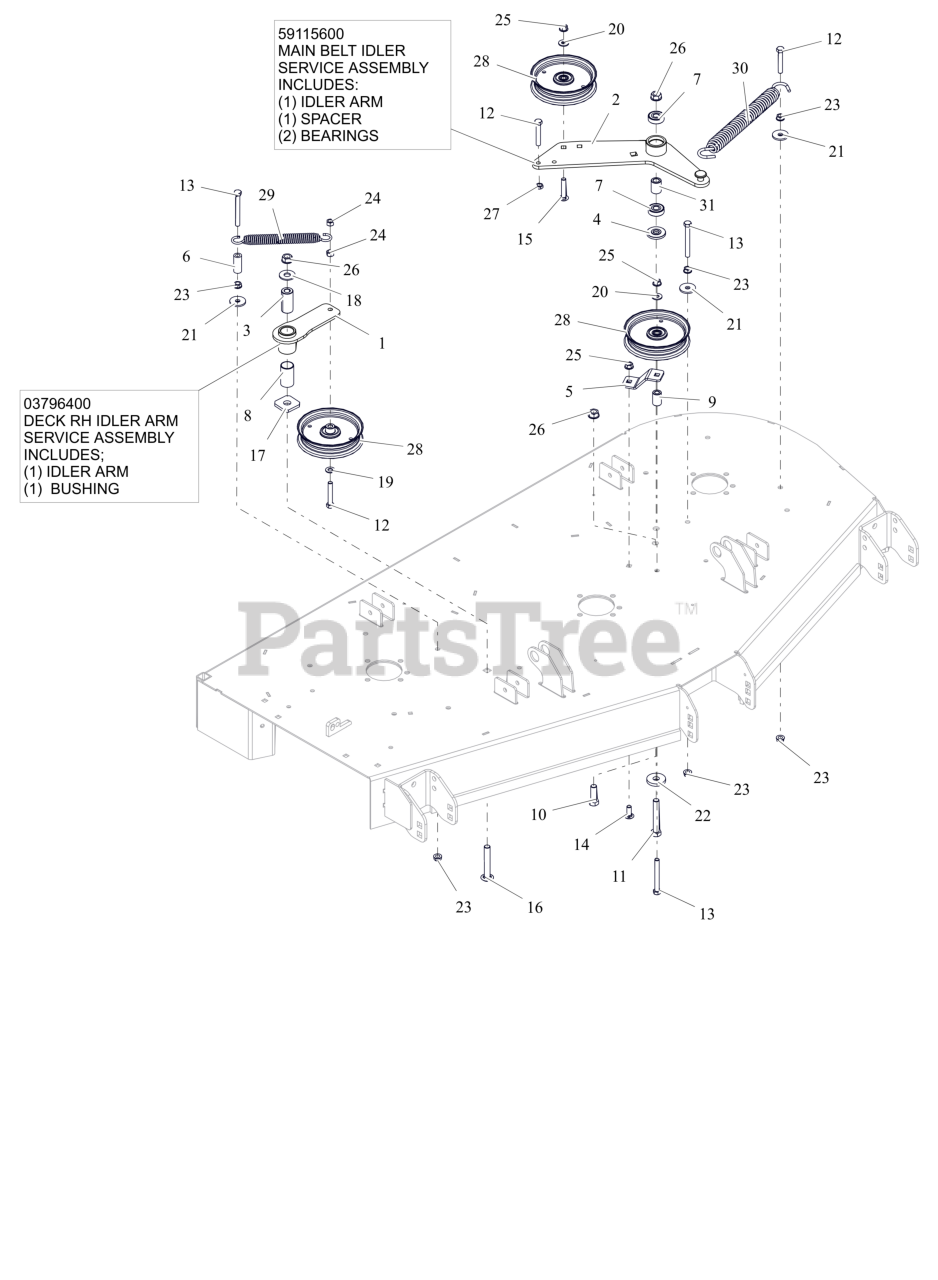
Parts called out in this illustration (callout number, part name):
1	WMT, IDLER ARM - BLACK
1	ASM, IDLER ARM (DECK)
2	WLDMT, DECK PTO IDLR ARM
2	ASSEMBLY, MAIN BELT IDLER
3	BSHG, SPCR .502X.997X2.03 PM
4	SPACER, IDLER ARM
5	PTO FIXED IDLER MTG BRKT-ORG
6	HOSE, .38 X 1.65
7	BRG-BALL .500X1.38X.437
8	BSHG, 1.00X1.125X1.937
9	BUSHING, SLV .380X.750X1.190
10	BLT,HEX .50-13X1.50 G5 ZCC
11	BLT,HEX .50-13X3.25 G5 ZCC
12	BLT,HEX .38-16X2.25 G5 ZCC
13	BLT, HEX .38-16X3.25 G5 ZCC
14	BLT,RHSSN .38-16X1.00 G5 ZCC
15	BLT,RHSSN.375-16X2.00 G5 ZCC
16	BTL,RHSSN .500-13 X 3.25 G5 ZCC
17	WSHR-FLT .640X1.75X.250
18	WSHR,FLT .563X1.375X.109 ZCC
19	WSHR,FLT .406X.812X.065 ZCC
20	WSHR,FLT .375X.875X.083 ZCC
21	WSHR,FLT .406X1.375X.135 ZCC
22	WSHR-FL-STL 0.557X1.625X0.25 ZCC
23	NUT, SPNLK-FLG .38-16 G5 ZCC
24	NUT-LK-CTR .38-16 ZC120
25	NUT-LK-CTR-FLG .375-16 GF ZCC
26	NUT-LK-CTR-FLG .500-13 GG ZCC
27	NUT-JAM .375-16 G2 ZCC
28	IDLER- FLAT - 5.00" X .75"
29	SPRING, EXTENSION
30	SPRING, EXTENSION
31	SPACER .510 X .867 X 1.1485
